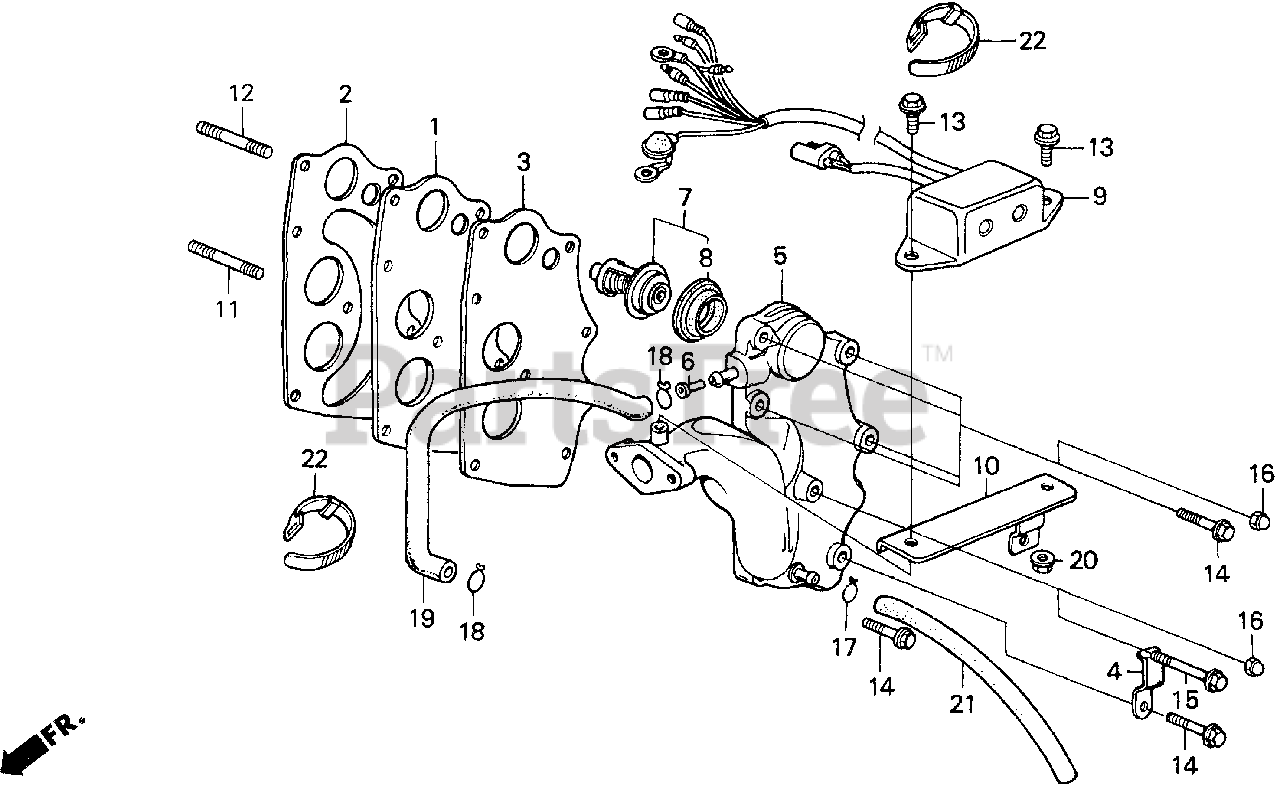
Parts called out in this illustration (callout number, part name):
1	PLATE, EX. CHAMBER
2	GASKET, EX. CHAMBER
3	GASKET, EX. CHAMBER
4	CLAMP, FUEL TUBE (NOT AVAILABLE)
5	MANIFOLD, IN. *NH8* (DARK GRAY)
6	NOZZLE, THROTTLE (NOT AVAILABLE)
7	THERMOSTAT ASSY.
8	RUBBER, THERMOSTAT
9	MODULE, IGNITION CONTROL (CDI)
10	STAY, IGNITION CONTROL MODULE
11	BOLT, STUD (6X48)
12	BOLT, STUD (6X36)
13	BOLT, FLANGE (6X12)
16	NUT, CAP (6MM)
17	CLIP, TUBE (B8)
18	CLIP, TUBE (B12)
19	TUBE, BYPASS
20	NUT, HEX. (6MM)
21	BULK HOSE, VACUUM (5X3000) (5X250)
22	BAND B1, CABLE
